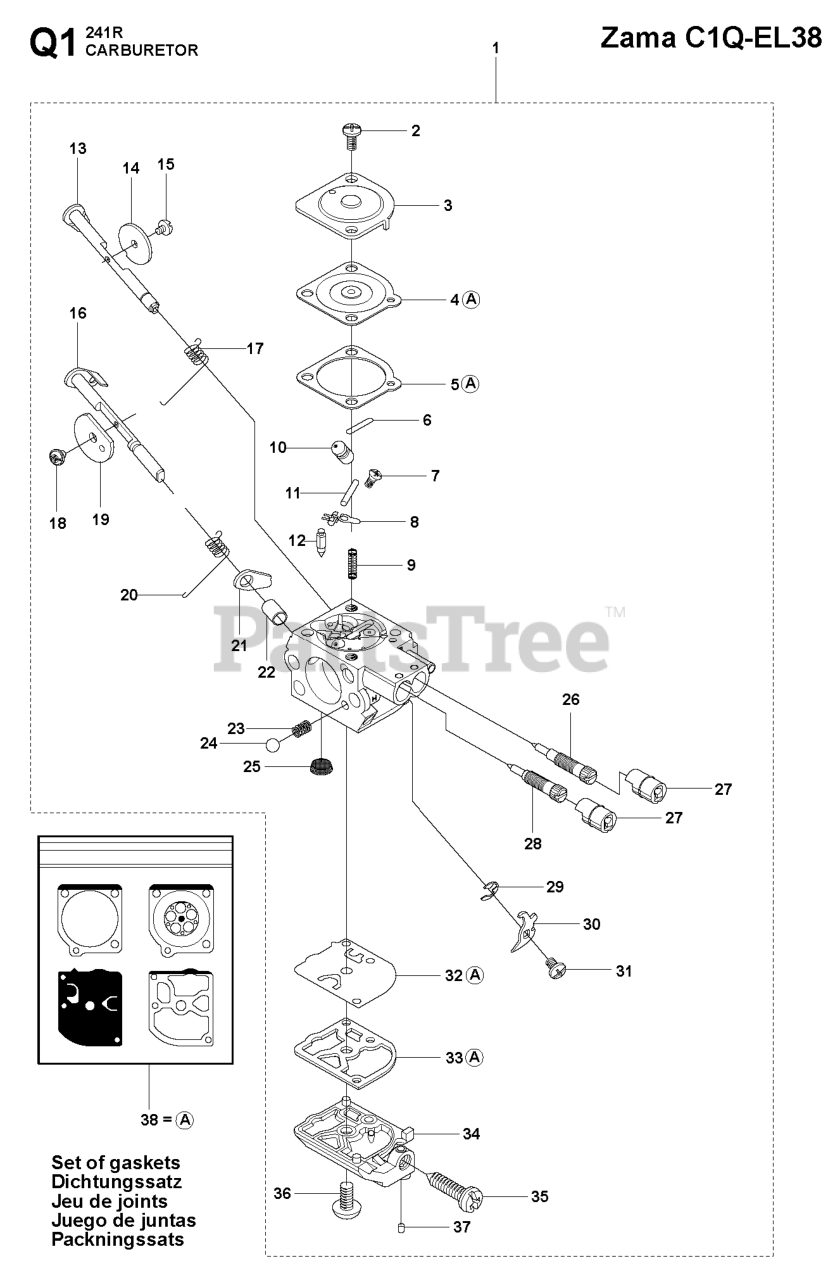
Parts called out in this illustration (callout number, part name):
1	CARBURETTOR C1Q-EL38
9	SPRING
11	PIN RETAINING SCREW
12	INLET NEEDLE
13	SHAFT ASSY
16	SHAFT ASSY
17	RETURN SPRING
25	FUEL INLET SCREEN
26	IDLE SCREW
27	LIMITER CAP KIT
28	SCREW
32	PUMP DIAPHRAGM
38	GASKET KIT (ZAMA GND39)
